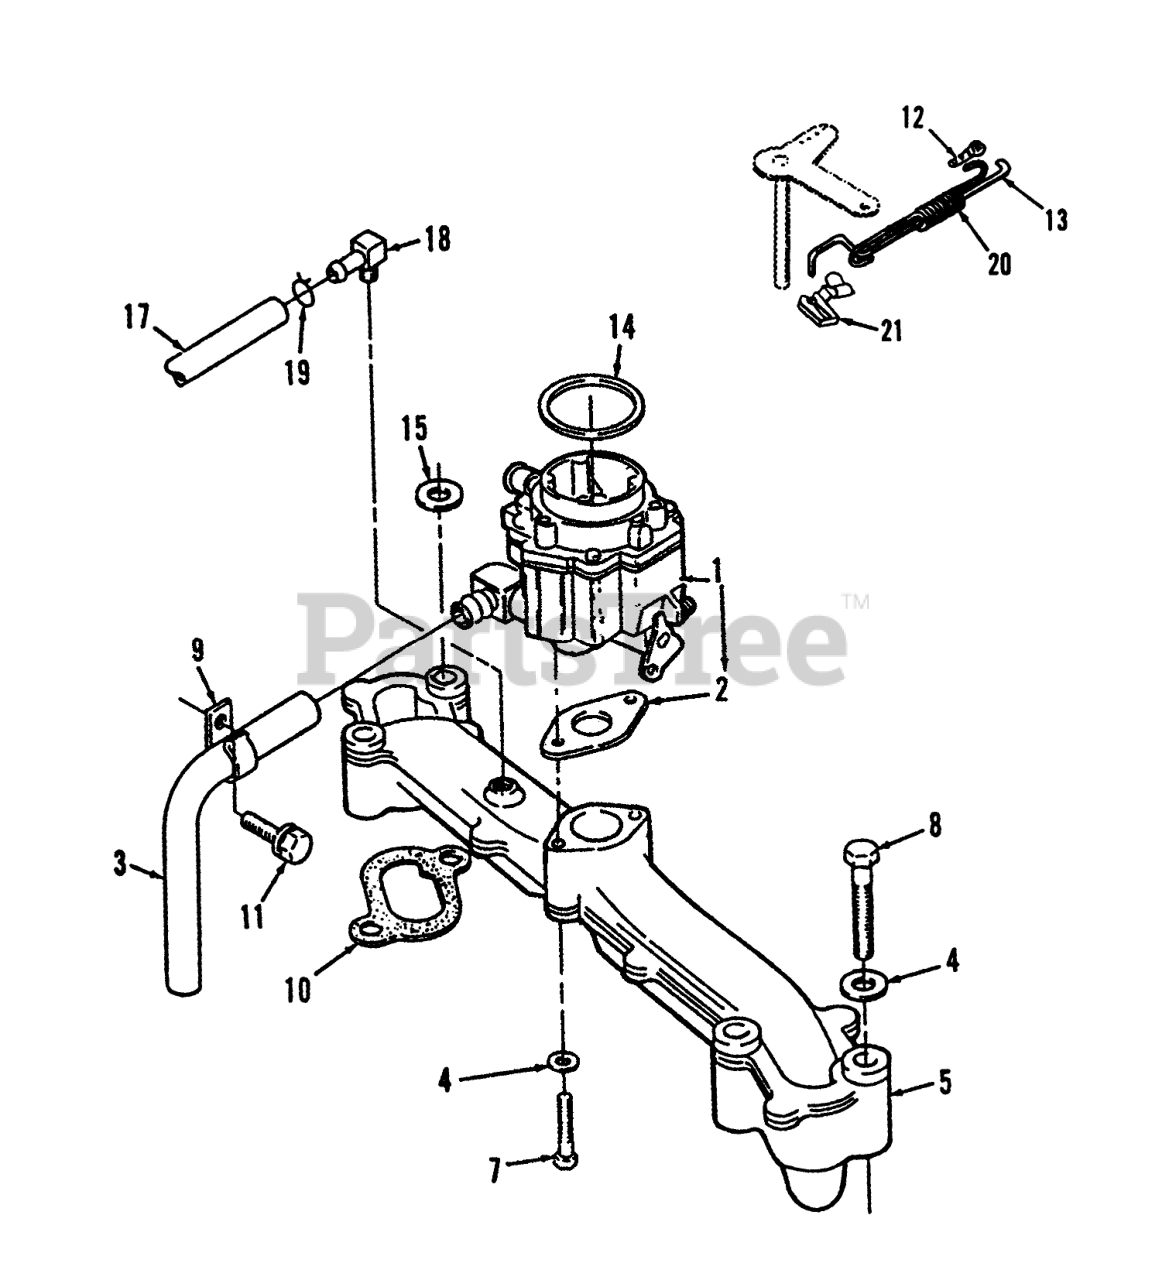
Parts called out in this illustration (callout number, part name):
1	Carburetor-Complete(Includes Mounting Gasket, Elbow, & O-Ring)(See Separate Page for Components)
2	Gasket
4	WASHER-FLAT
5	Intake Manifold
7	Bolt
9	Clip
10	GASKET
11	SCREW-HWH
12	Retaining Clip
13	Rod-Governor Control
15	FLAT WASHER
16	FLAT WASHER
17	HOSE-RUBBER, BREATHER
18	FITTING-BARB
19	CLAMP-HOSE
20	Spring-Governor Rod
21	Clip-Retaining
